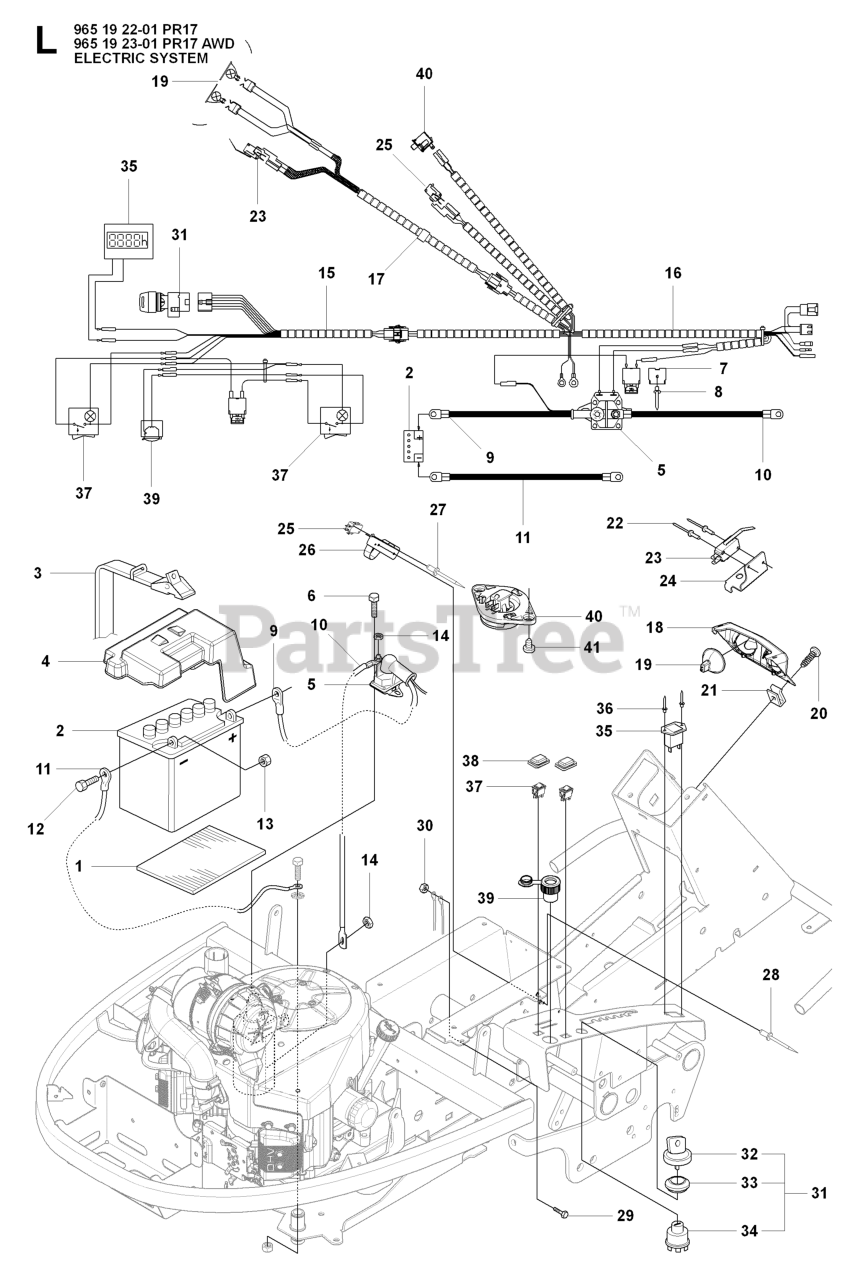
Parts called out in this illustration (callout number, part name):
2	BATTERY - DRY
15	WIRING CONTROL PANEL
23	RP MICRO SWITCH
25	%BRAKER
35	HOUR METER
40	ANTI-START SWITCH CPL
41	SCREW
